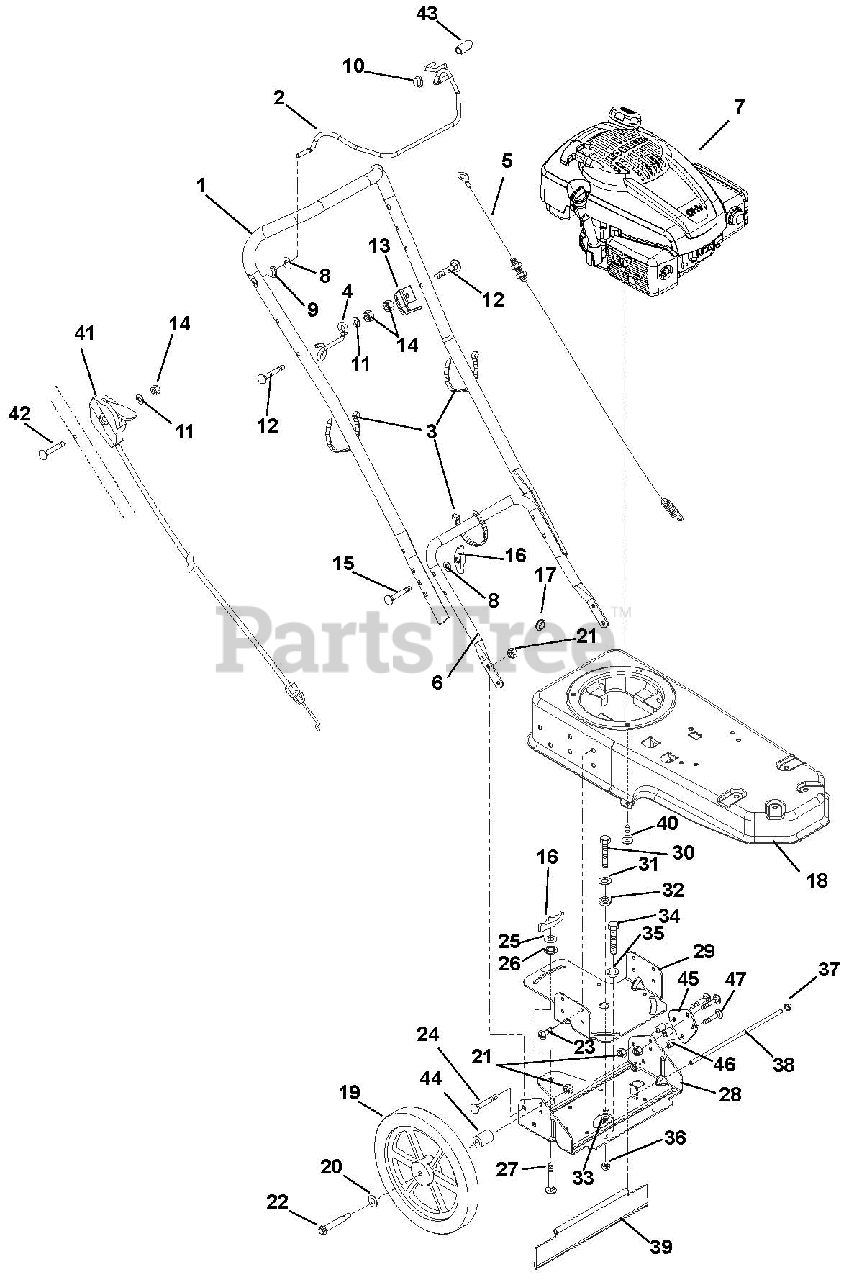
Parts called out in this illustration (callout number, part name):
1	Handlebar, Upper
2	Bail, Clutch Control
3	Cable, Tie
4	Guide, Pullcord
5	Cable, Control
6	Handlebar, Lower
7	Engine, Courage XT-8, Kohler
8	Washer, Flat Steel .344 x .688 x .065
9	Bushing, Flange .325 x .444 x .440 x .560
10	Nut, Push .25
11	Washer, Flat Steel .281 x .62 x .065
12	Bolt, Round Head Extra Long Square Neck .25-20 x 1.25
13	Cable, Anchor
14	Nut, Locking Center .25-20
15	Bolt, Round Head Square Neck Full Thread .31-18 x 2.00 Grade 5
16	Knob, Wing .312-18
17	Grommet .50 I.D.
18	Frame, Trimmer
19	Wheel 14" String Trimmer
20	Washer, Flat Steel .52 x .827 x .062
21	Nut, Locking Center .38-16
22	Bolt, Shoulder .38-16 x 2.50
23	Screw, Tapping .38-16 x .75
24	Bolt, Round Head Square Neck .38-16 x .75 Grade 5
25	Washer, Flat Steel .38 x .875 x .083
26	Nut, Push .312
27	Bolt, Round Head Square Neck .31-18 x 1.00
28	Bracket, Axle Swivel
29	Base, Swivel
30	Bolt, Hex .50-13 x 1.00 Grade 5
31	Washer, Flat Steel .562 x 1.38 x .109
33	Nut, Locking Center .50-13
34	Bolt, Hex .31-18 x 1.00
35	Bushing, Flange .312 x .500 x .344 x .880
36	Nut, Locking Center .31-18
37	Nut, Push .312
39	Guard, Rear Swivel
40	Screw, Tapping .38-16 x 1.00
41	Cable, Throttle
42	Bolt, Round Head Extra Long Square Neck .25-20 x 1.75
43	Cap, Vinyl .25 I.D.
44	Bushing, Sleeve .377 x .624 x .235
45	Bracket, Trimmer Wheel
46	Bushing, Sleeve .469 x .750 x .430
47	Bolt, Round Head Square Neck .38-16 x 1.50 G5YZ
